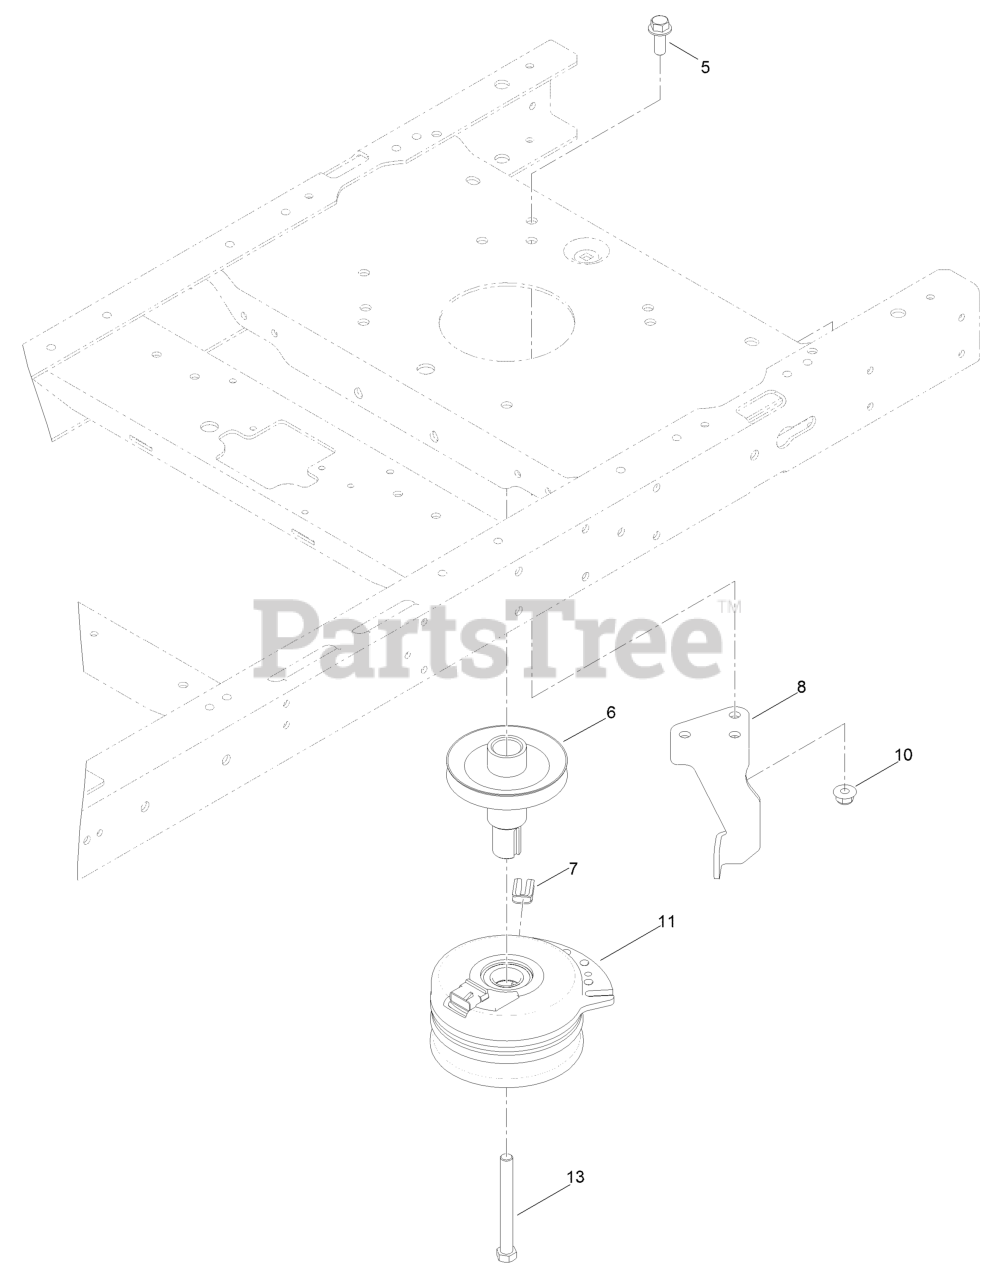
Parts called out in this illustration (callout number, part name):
5	SCREW-HHF 3/8-16 X 1
6	PULLEY-ENGINE
7	ISOLATOR-CLUTCH
8	STOP-CLUTCH (NARROW)
10	NUT-HF, NI
11	CLUTCH-ELECTRIC
13	PIN-ROLL, SLOTTED
